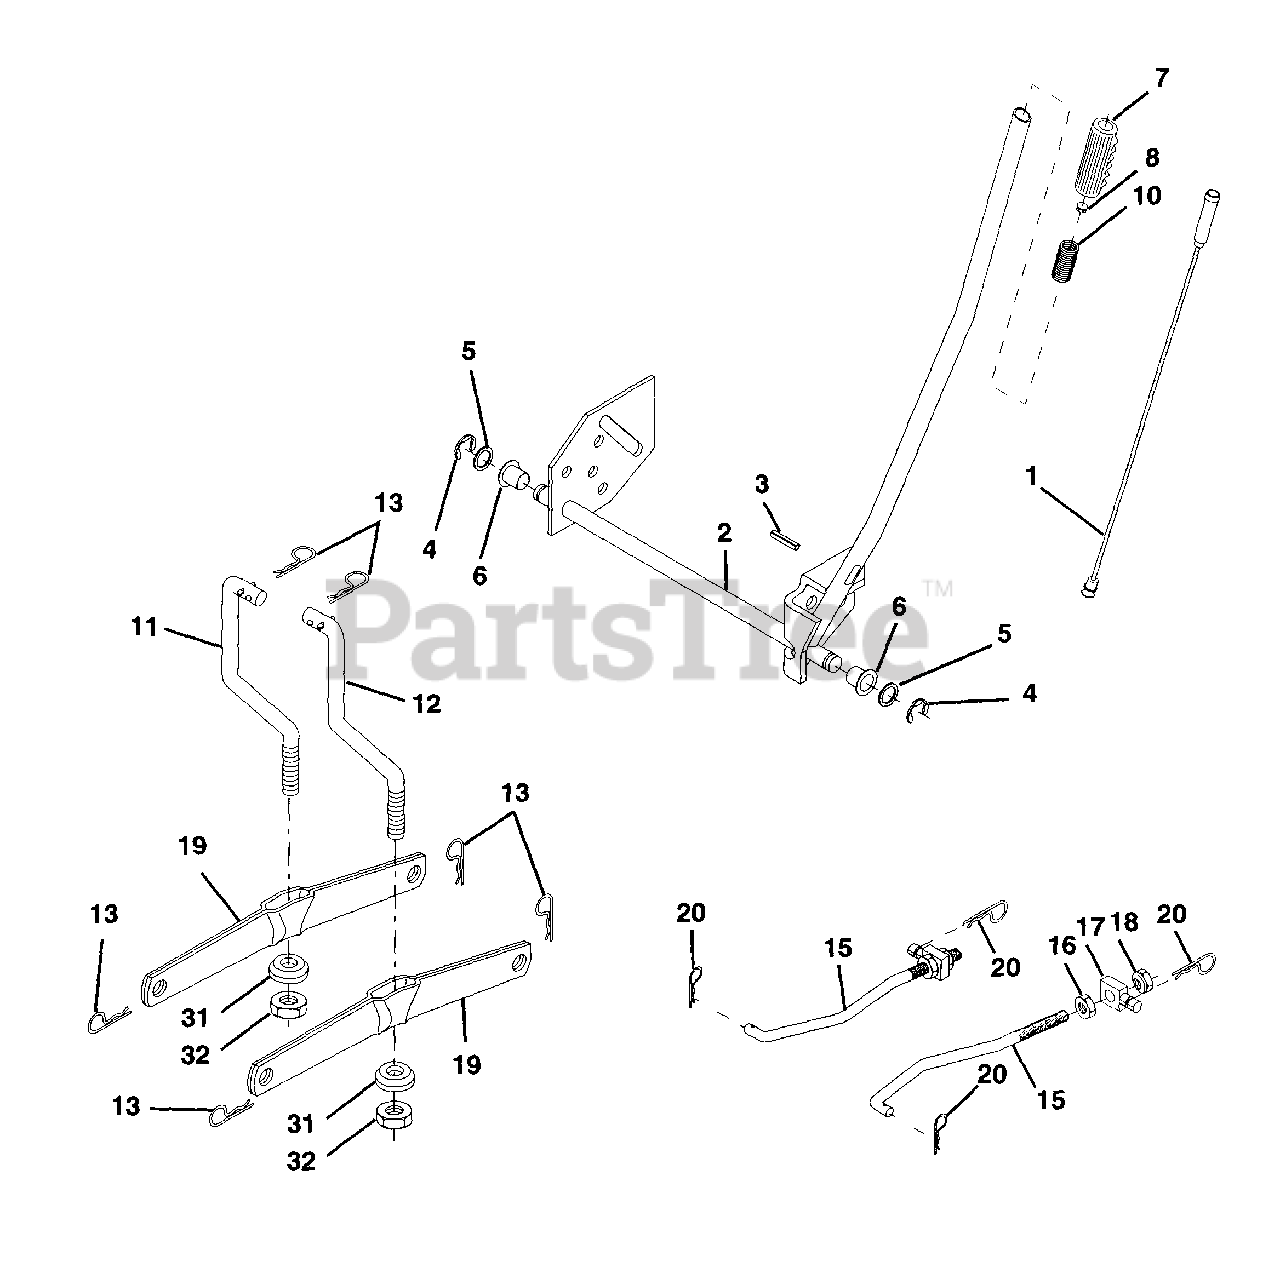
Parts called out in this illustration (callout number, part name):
1	Wire Asm Inner W/plunger 17 32
2	Shaft Asm Lift
3	Pin Groove
4	E Ring #5133-62
5	Washer PLTD 21/32 x 1 x 21ga
6	Bearing Nylon Blk 629 Id
7	Grip Handle Bicycle
8	Button Plunger Black
10	Spring Cprsn 3 750 Oiled
11	Link Lift LH
12	Link Lift RH
13	Retainer Spring
15	Link Front
16	Nut Jam Hex 1/2-13 Unc
17	Trunnion Blk Zinc
18	Nut Lock W/wsh 1/2-13unc
19	Arm Suspension Rear
20	Spring, Retainer
31	Bearing Pvt. Lift Spherical
32	Nut Crownlock 3/8-24
